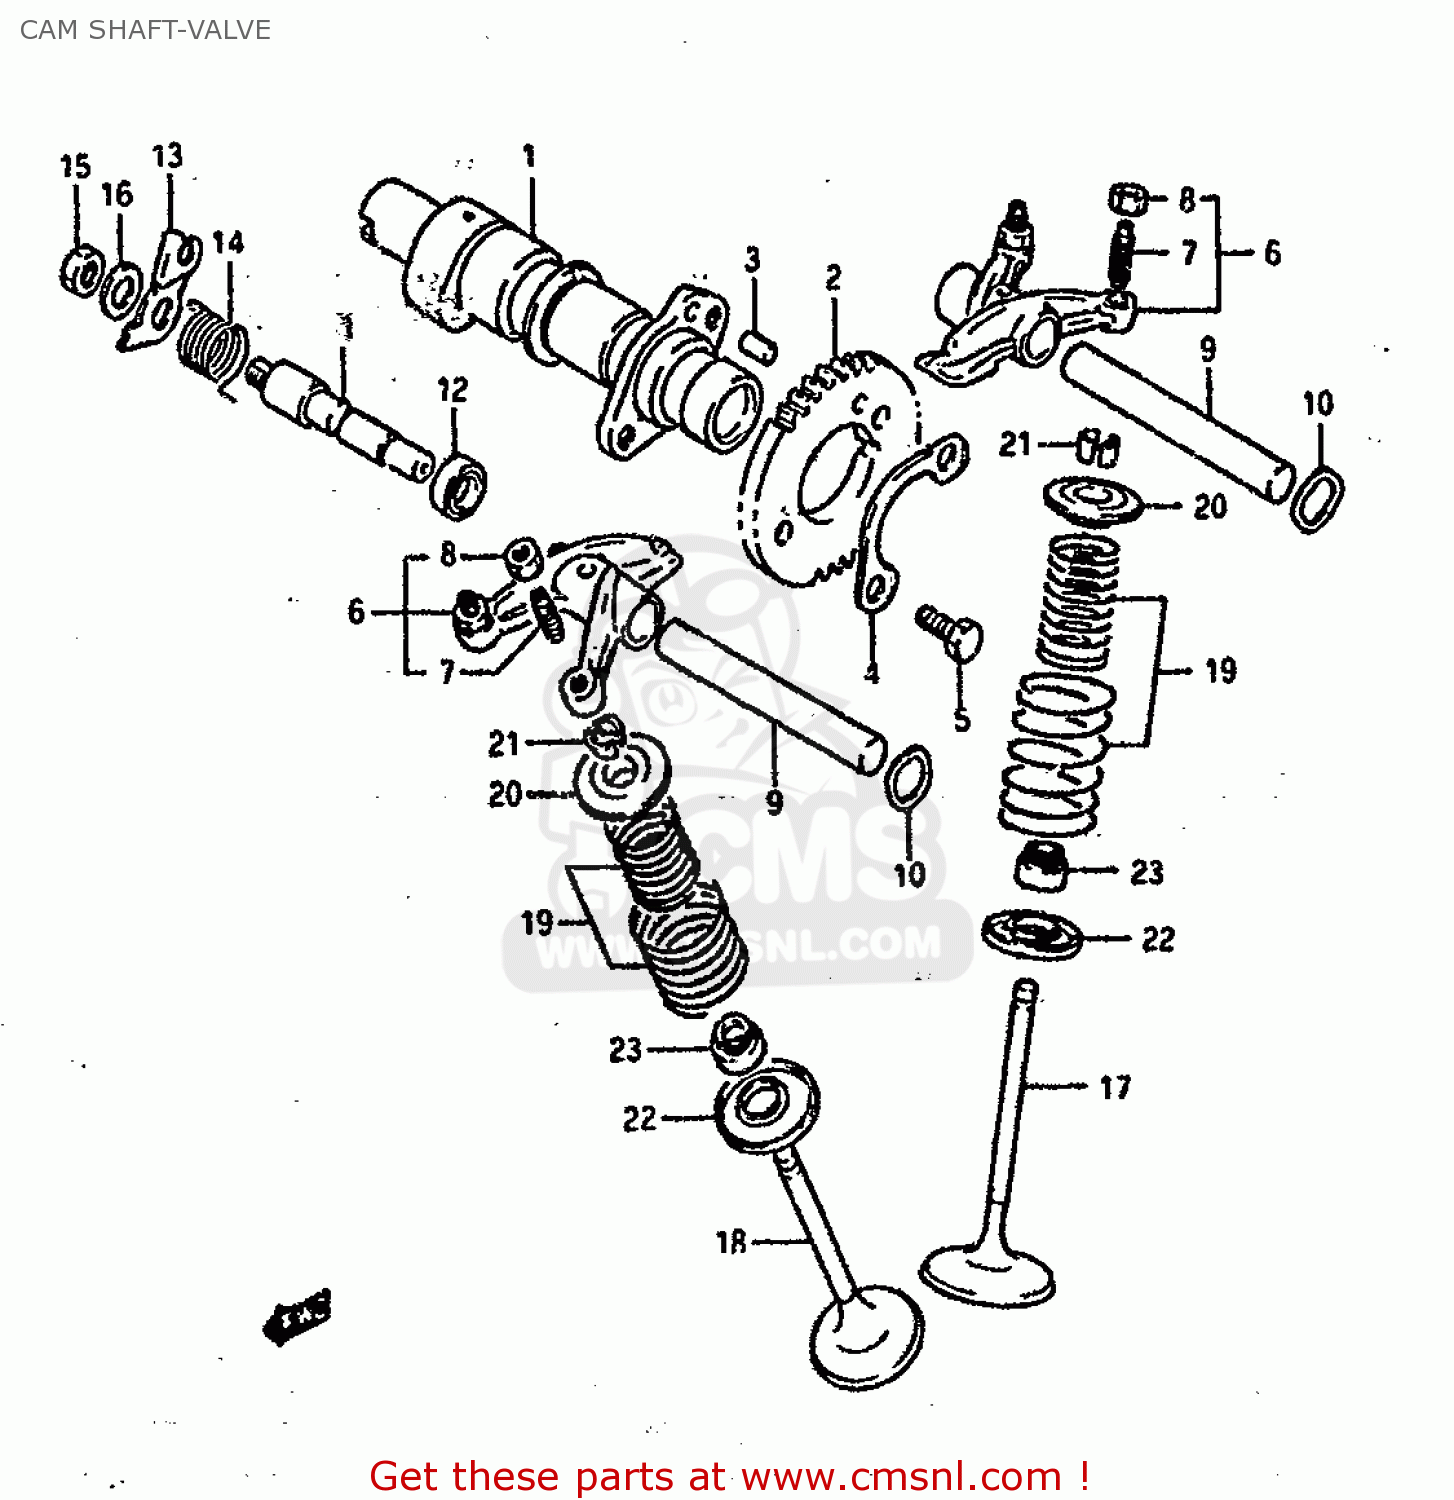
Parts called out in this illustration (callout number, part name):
1	CAMSHAFT
2	SPROCKET,CAMSHAFT
3	PIN
4	WASHER,SPROCKET
5	BOLT(6X14)
6	ARM,VALVE ROCKER
7	SCREW,TAPPET ADJUSTING
8	NUT,ADJUSTING SCREW
9	SHAFT,VALVE ROCKER ARM
10	WASHER
11	SHAFT,DECOMP
12	SEAL,OIL(10X17X6)
13	LEVER,DECOMP SHAFT
14	SPRING
15	NUT 8MM
16	WASHER
17	VALVE,INTAKE
18	VALVE,EXHAUST
19	SPRING SET,VALVE
20	RETAINER,VALVE SPRING
21	COTTER,VALVE
22	SEAT,VALVE SPRING
23	SEAL,OIL(7X14.4X9)
